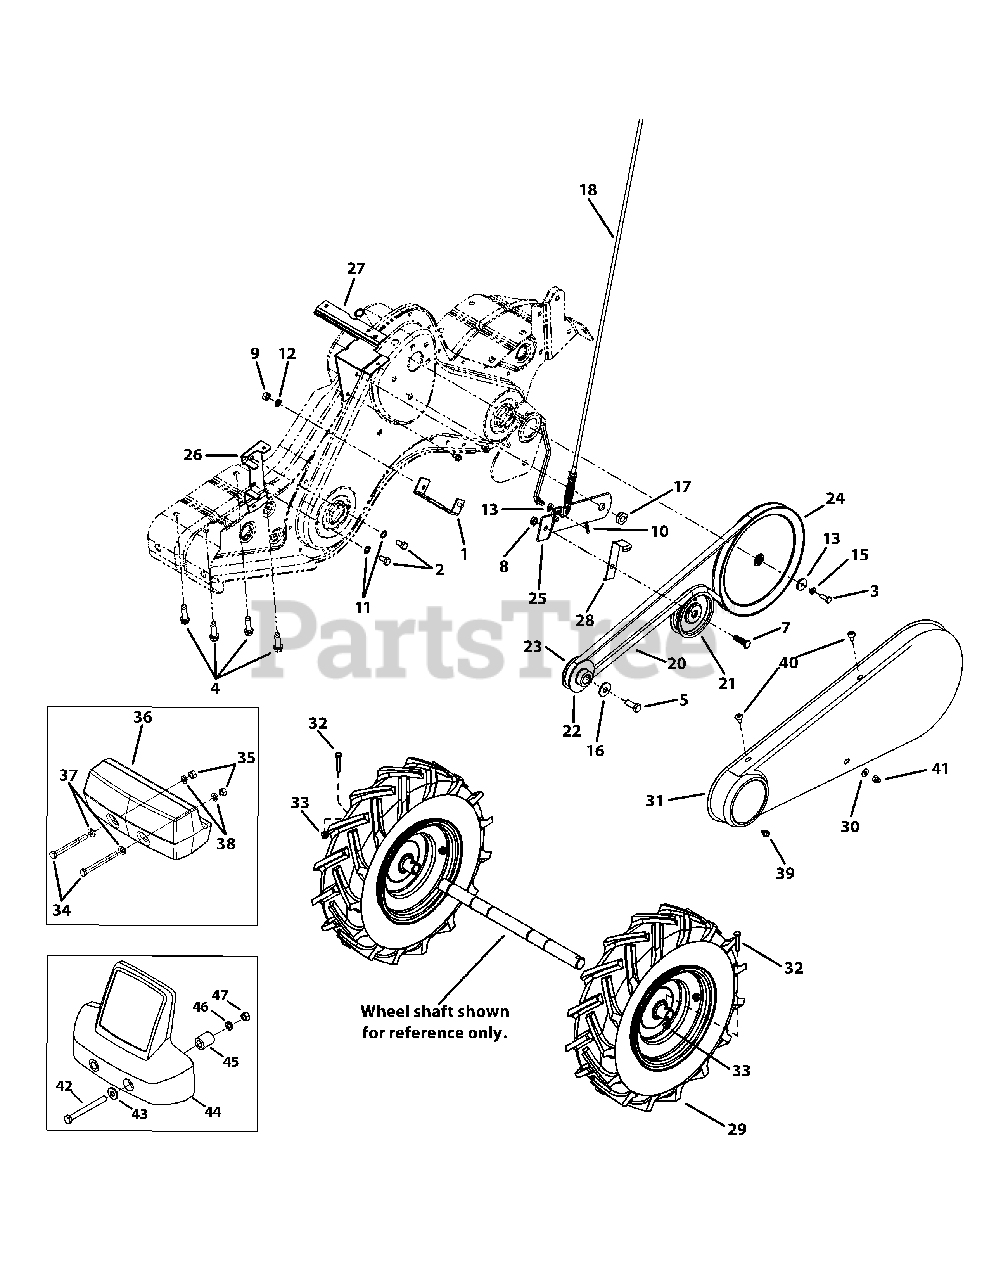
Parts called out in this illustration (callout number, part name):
1	Belt Cover Brkt Ass’y
2	Hex Screw 5/16-24 x .62
3	Hex Scr 1/4-28 x .75
4	Hex S-Tapp Scr 3/8-16 x 1.5 Gr. 5
5	Hex L-Scr 3/8-24 x 1.00" Lg. Gr. 8
6	Hex Wash S-Tapp Scr 1/4-20 x .50
7	Hex Screw 3/8-16 x 1.25 Gr. 5
8	Hex Cent L-Nut 3/8-16 Gr. 5
9	Hex Nut 5/16-18
10	Int. Cotter Pin 5/16 Dia.
11	Internal L-Washer
12	L-Wash 5/16 ID
13	Flat Washer .25 ID x .93 OD x .125
14	Shakeproof Spring Washer
15	L-Wash 1/4 ID
16	Belleville Washer
17	Shoulder Nut
18	Clutch Cable
19	Idler Pulley Rod
20	Belt: 4L x 58.16" Lg.
21	Flat Idler w/flanges 3-3/4" OD
22	Outer Engine Pulley Half
23	Inner Engine Pulley Half
24	Input Pulley
25	Idler Bracket
26	Belt Keeper Brkt.
27	Shift Cover Brkt.
28	Idler Belt Keeper
29	Wheel Ass'y 16.0 x 4.6 x 8
30	Flat Washer .266 ID x .625 OD
32	Hex Cap Screw1/4-20 x 1.5" Lg.
33	Flange Locknut 1/4-20
34	Hex Bolt 1/2-13 x 5.00" Lg.
35	Hex Nut 1/2-13
36	Counterweight 40 Lbs.
37	Flat Washer .510 ID x 1.0 OD x .125
38	L-Washer 1/2" ID
39	Hex Wash HD Tapp Scr 1/4-20 x .38
40	Torx Mach. AB-Tapp Scr. 1/4 x .62" Lg.
41	Hex Lock Stop Nut 1/4-28
42	Hex Hd. Scr. 1/2-13 X 5.5
43	Flat Washer 1/2 x 1.25 x .100
44	Counterweight
45	Hub, .636 ID x 1.0 OD x .94
46	Lockwasher 1/2
47	Hex Nut 1/2-20
